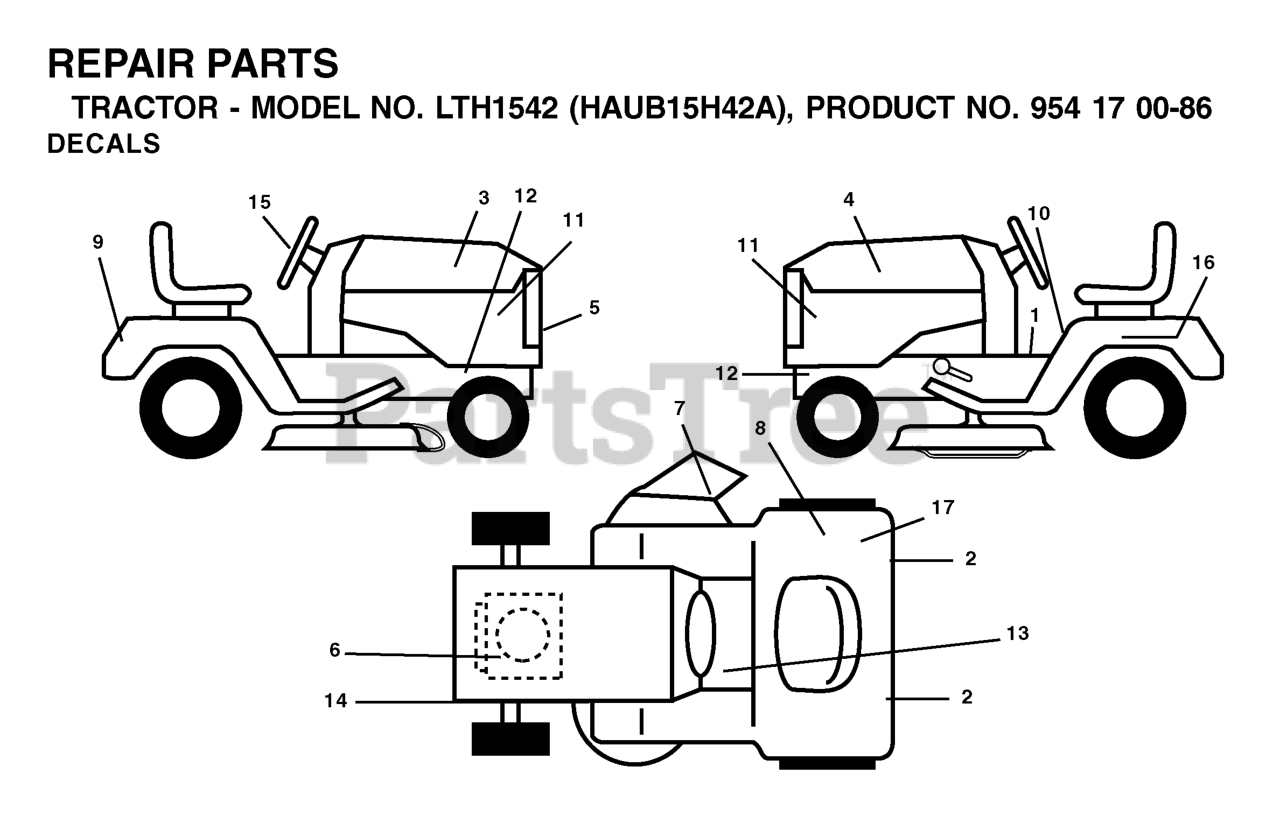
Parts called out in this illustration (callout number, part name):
1	IDLER SPINDLE
2	NUT 1/2-13 HEX NYLOC ZD
3	HCS 1/2C X 2 3/4
6	BATTERY, 12 V 330 AMP
7	GROMMET, BUMPER
10	BOLT 5/16-18 X 3/4
11	BATTERY HOLD DOWN
12	PUSH NUT-NYLON
13	BOLT - 1/4-20 X 7.5
14	BRACKET, DECK HANGER
15	SPRING, RETURN TO NEUTRAL
16	REAR SEAT SUPPORT ORANGE
17	PUMP IDLER WELDMENT
18	SPRING, SEAT
19	CAP, SPRING COVER
20	PULLEY, IDLER RAKE & ZTR
21	MOTION LIMITER
22	BELT, HYDRO PUMP
23	GROMMET, FUEL LINE
24	SCR #10-12X1-1/2HEX WASH HD ZD
25	MOUNTING BLOCK CABLE TIE
26	TIE, PLASTIC
27	HCS 5/16C X 3/4
28	HCS 5/16-18X2
30	HCS 3/8C X 1 1/4 GR5
31	NUT.1/4-20.HEX.NYLOC.ZD
32	SCREW 1/4 X 5/8
33	WASHER 3/8 FLAT
34	NUT 3/8C CENTERBLOCK
35	WASHER 1/2 FLAT
36	NUT 5/16C WHIZ
37	HCS 3/8C X 1 1/2
38	NUT 5/16 NYLOC
39	BRACKET, FRT SUPPORT, BLACK
